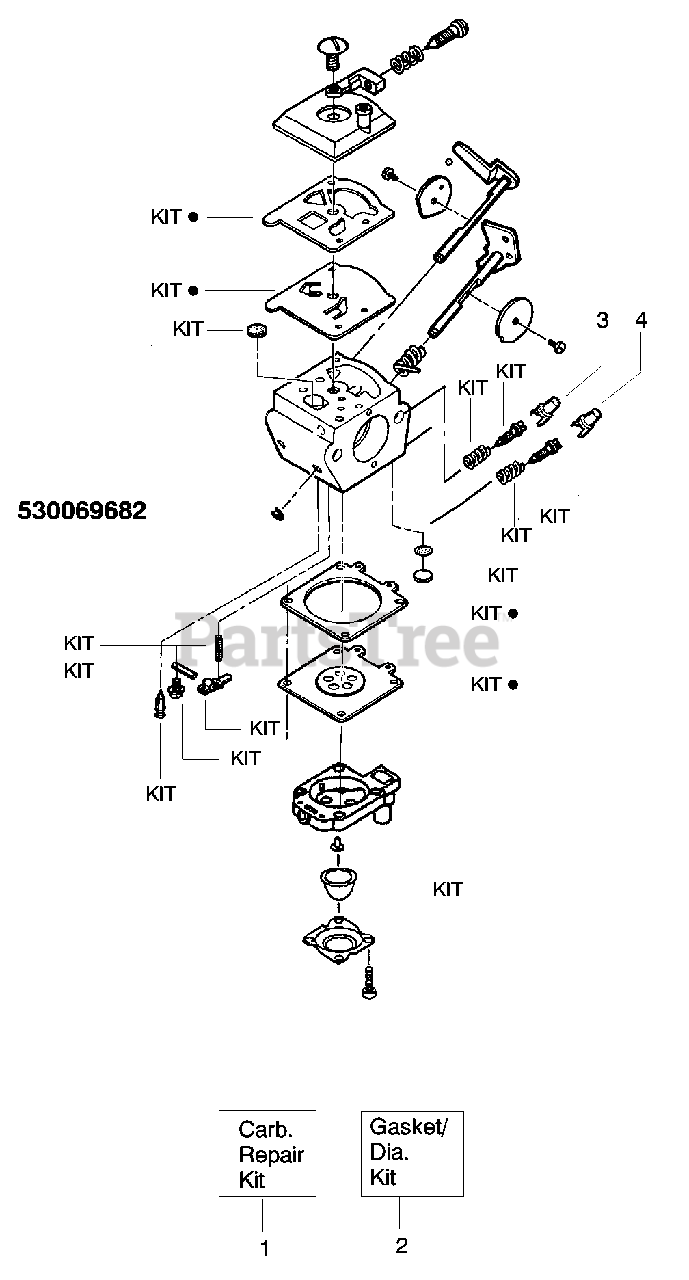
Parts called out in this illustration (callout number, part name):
1	Kit-Carb. Repair
2	Kit-Gasket/Diaphragm
3	Limiter Cap (Low) tan
4	Limiter Cap (High) brown
530069682	Carburetor Assembly
